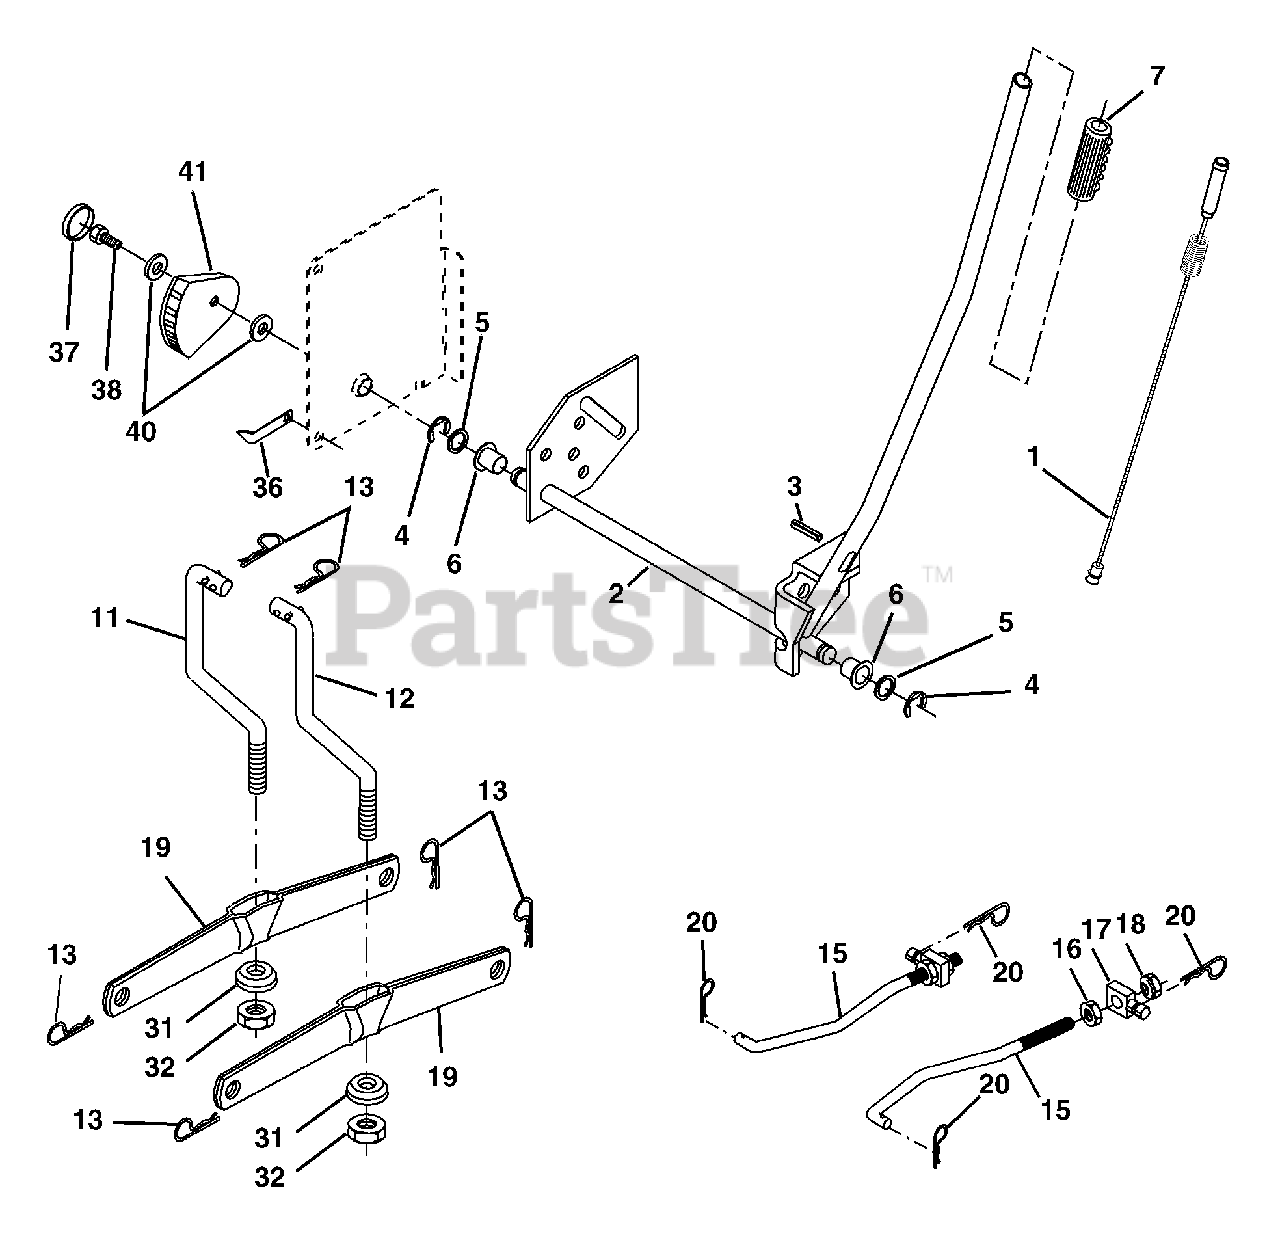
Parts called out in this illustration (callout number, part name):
1	Plunger Assembly
2	Shaft Assembly, Lift
3	Pin, Groove
5	Washer 21/32 x 1 x 21 Ga.
6	Bearing, Nylon
7	Grip, Handle, Fluted
11	Link, Lift, L.H.
12	Link, Lift, R.H.
13	Retainer Spring
15	Link, Front
16	Nut, Hex, Jam 1/2-13 unc
17	Trunnion
18	Locknut, Hex, with Washer Insert 1/2-13 unc
19	Arm, Suspension, Rear
20	Retainer Spring
31	Bearing, Pvt, Lift
32	Nut, Crownlock 3/8-24
36	Pointer Height Indicator
37	Plug Hole
38	Screw 5/16-18 x 1
40	Washer 11/32 x 1-1/2 10 Ga.
41	Indicator Height
